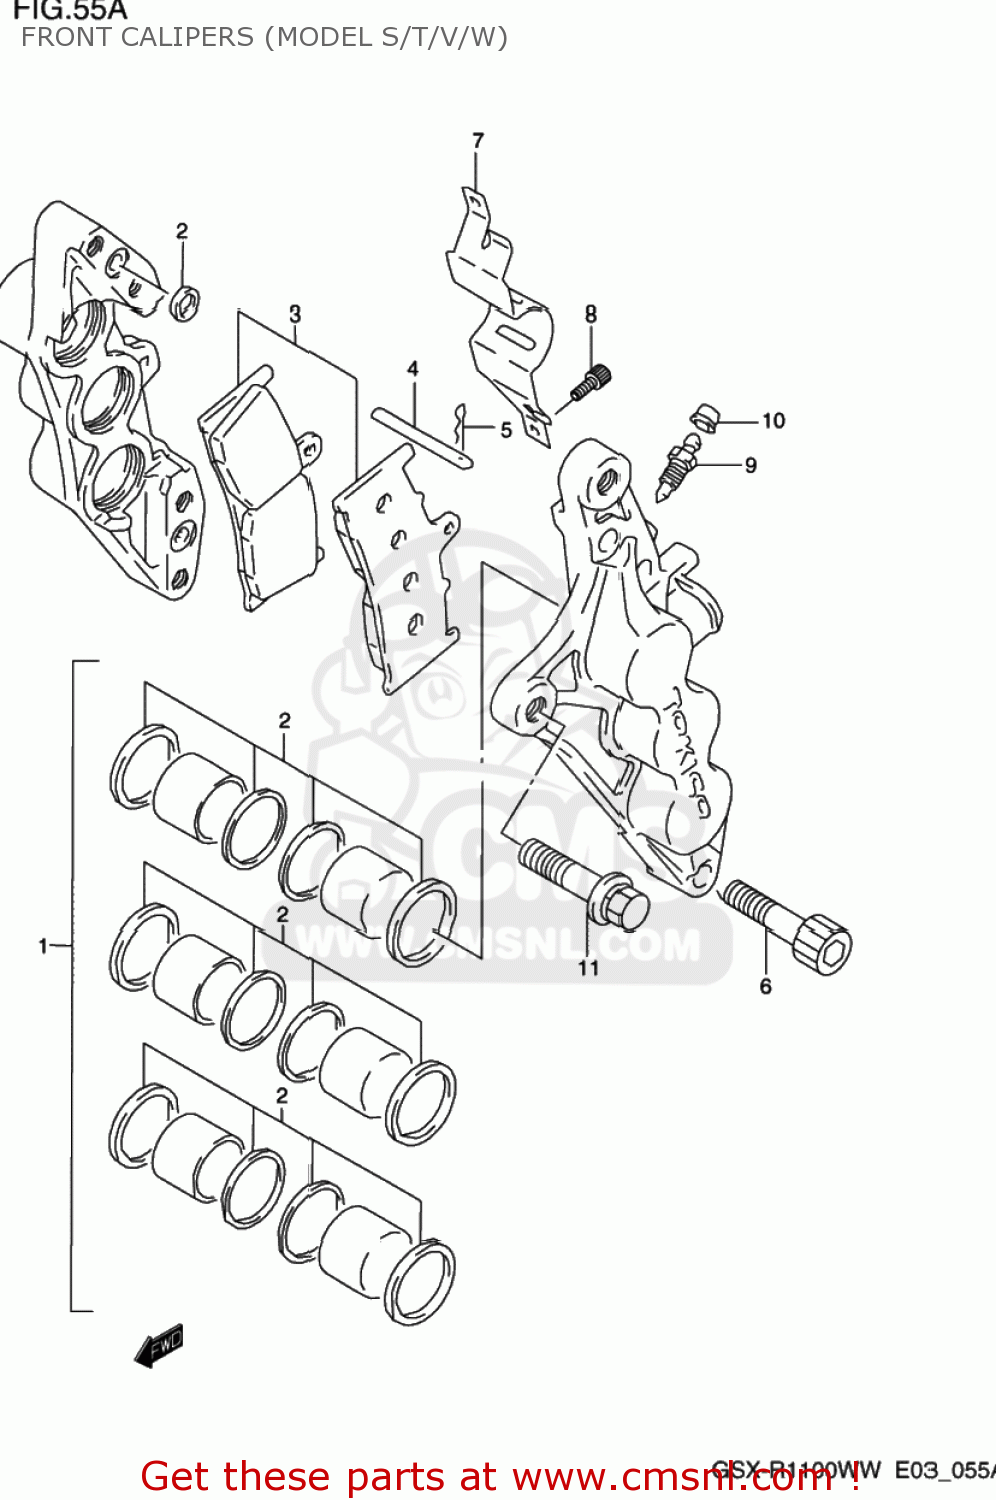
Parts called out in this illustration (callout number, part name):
1	PISTON SET
2	SEAL SET,PISTON
3	PAD SET (NAS)
4	PIN,PAD
5	CLIP,PAD PIN
6	BOLT,CALIPER
7	COVER,CALIPER
8	SCREW
9	BLEEDER
10	CAP,BLEEDER PLUG
11	BOLT
